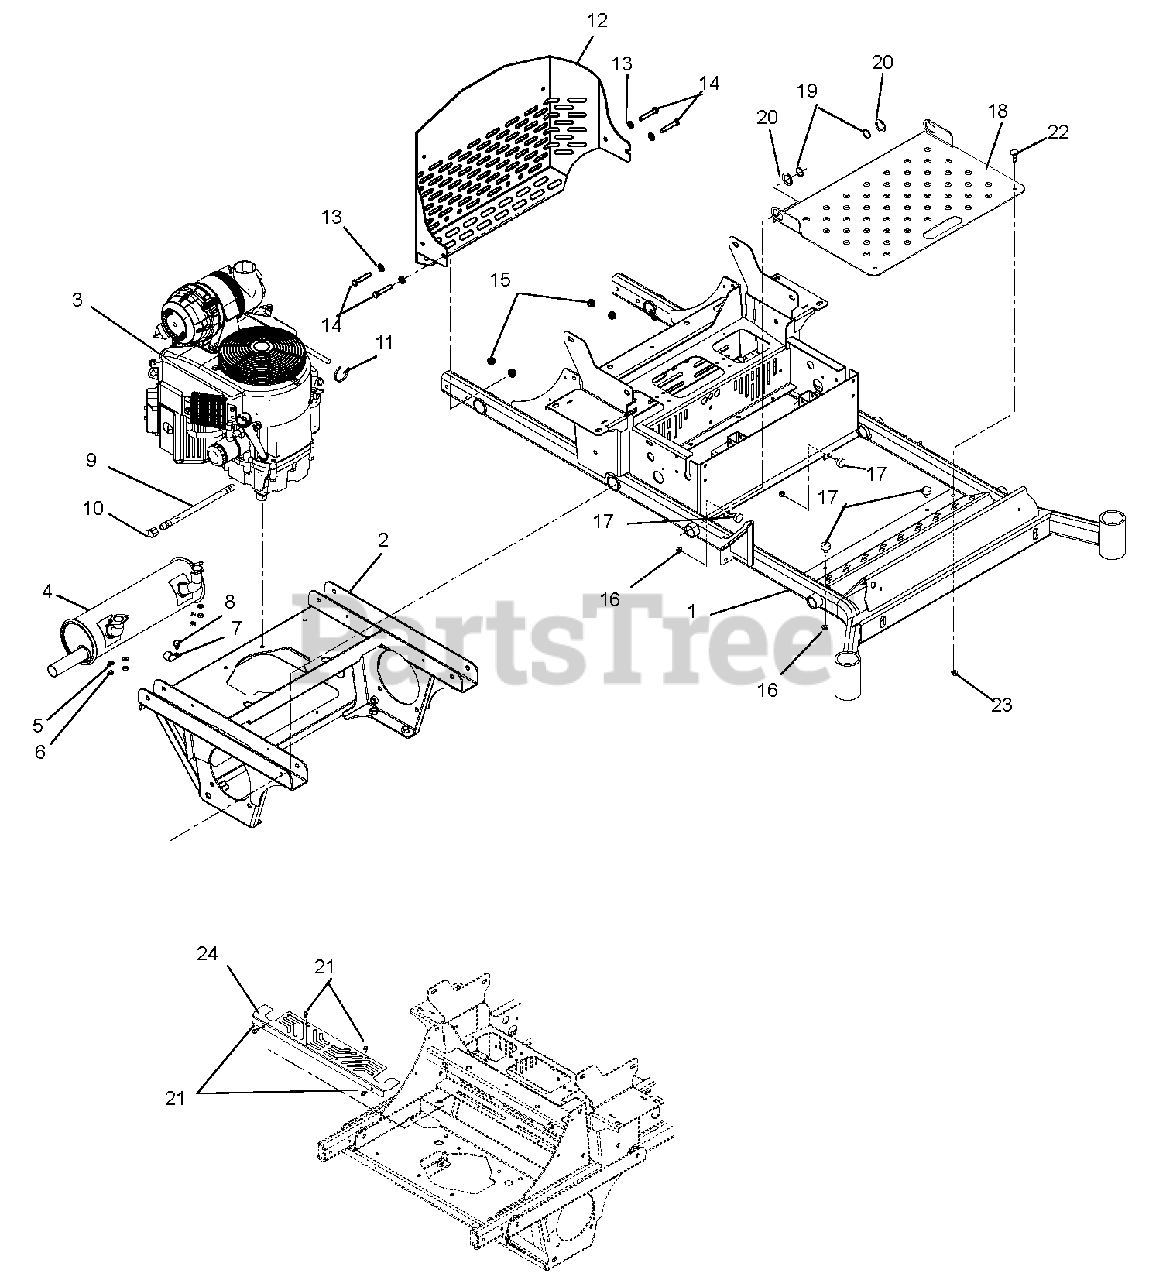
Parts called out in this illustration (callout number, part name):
1	Weldment, PT200 CE Frame
2	Weldment, 200PT Axle/Engine Frame
3	Engine, Kawasaki FX730 (26HP)
4	Muffler, Kawasaki Fixed 24/26HP
5	Washer, Lock .31 x .078 REG YWZC
6	Nut, Locking Top M8-1.25 YWZC
8	Screw-TAP .38-16 x .50 Hex Washer Head TR YWZ
9	Hose,Hydraulic .38-14-0K M6N0-M6N0
10	Pipe Cap 3/8 NPT Female
11	Cable Tie LG 5-1/2
12	Bumper, CE Rear
13	Washer, Flat Steel.406 x .812 x .065 YWZ
14	Bolt-Hex .38-16 x 2.25 GR5 YWZC
15	Nut, Locking Nylon-Flange .38-16 YWZC
16	Nut-Spin Lock-Flange .312-18
17	Bumper, Rubber
18	Inspection Panel
19	Ring, Retaining, External 1.00 x .078
20	Washer, Flat-Steel 1.010 x 1.505 x .062
21	Screw, Tapping .25-20 x .50 Hex Washer Head
22	Bolt, Round Head Square Neck .31-18 x 1.00 Grade 5
23	Nut, Locking-Nylon-Flange .31-18
24	Guard, CE Rear Access
